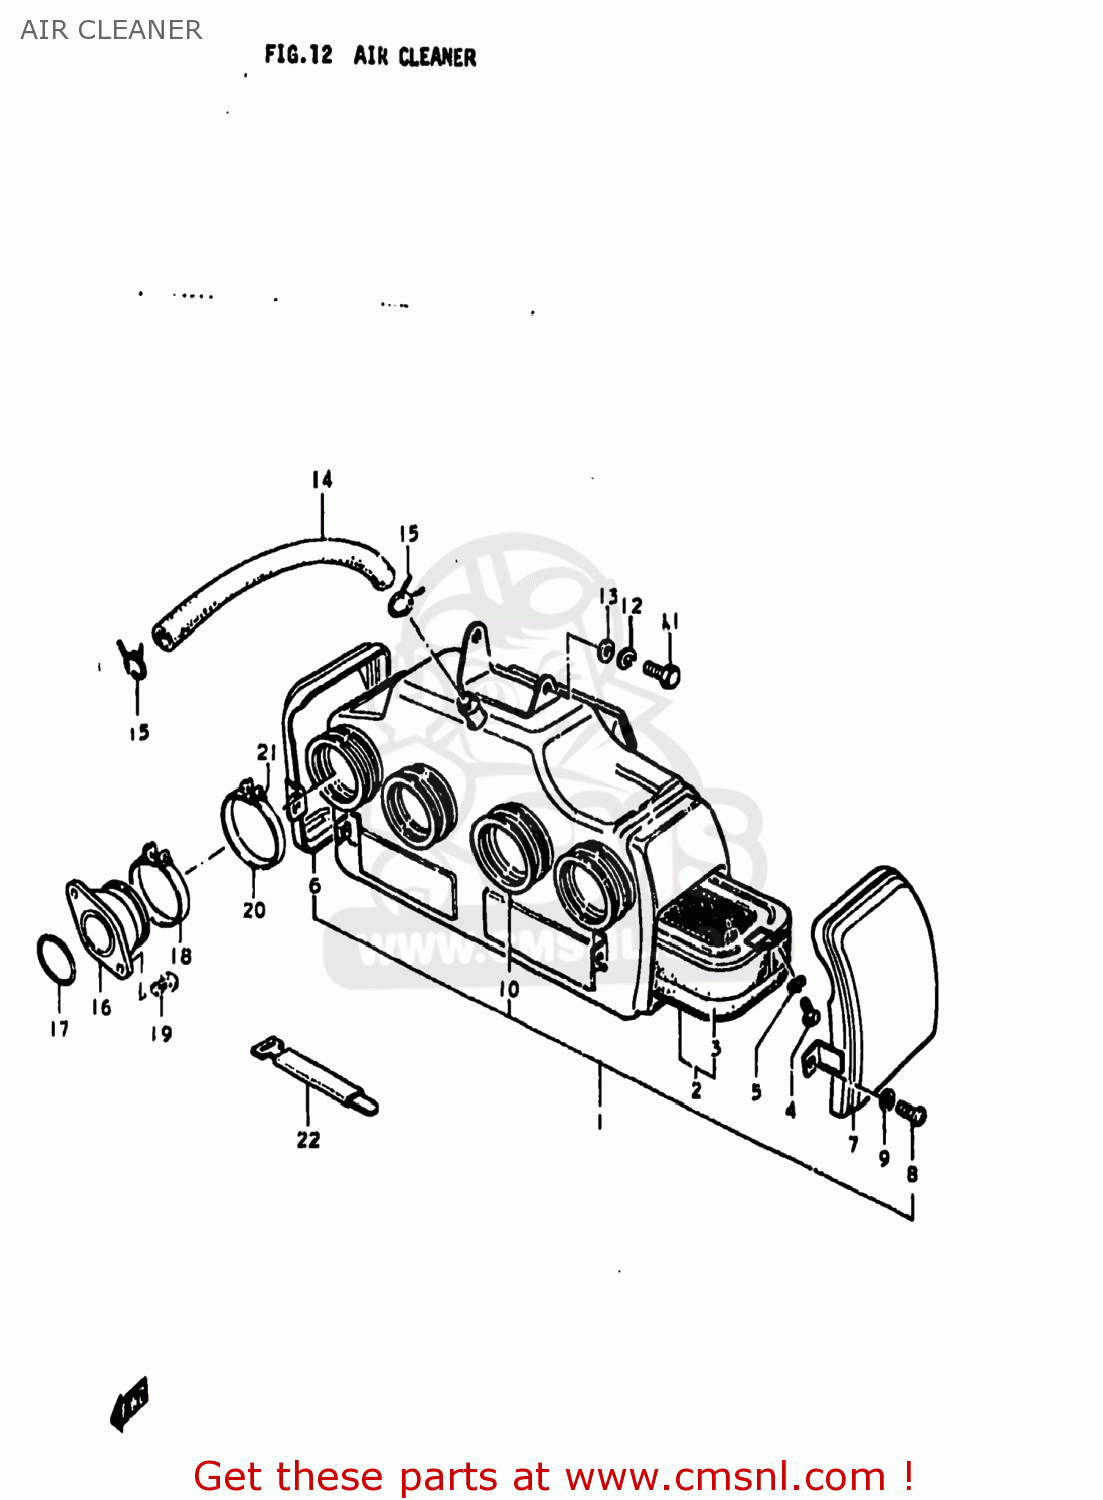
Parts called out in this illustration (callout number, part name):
1	CLEANER ASSEMBLY,AIR
2	FILTER ASSY,AIR CLEANER
3	FILTER
4	SCREW
5	LOCK WASHER
6	CAP,AIR CLEANER
7	COVER,AIR CLEANER,LEFT
8	SCREW
9	LOCK WASHER
10	HOSE
11	BOLT
12	LOCK WASHER
13	WASHER
14	HOSE
15	CLIP
16	PIPE,INTAKE
17	O RING(D:2.4,ID:31.7)
18	CLAMP
19	SCREW
20	CLAMP
21	SCREW TAPP.
22	CLAMP(L:120)
